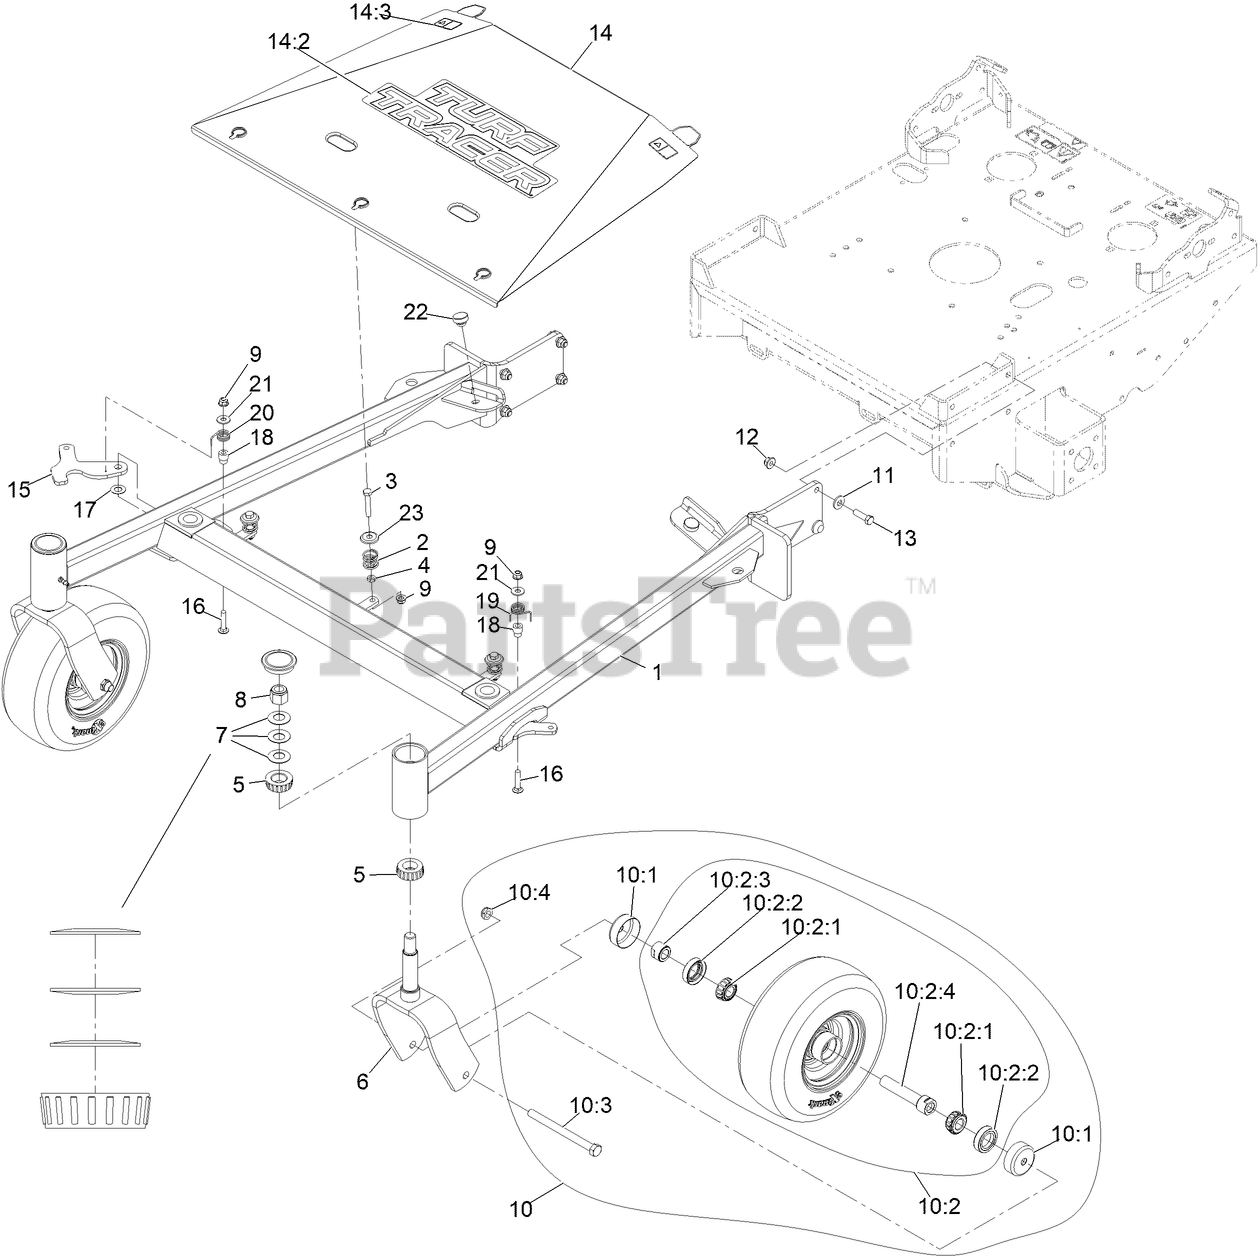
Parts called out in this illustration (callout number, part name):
1	ASM-60" Ttx Front Frame
3	SCREW-HH
4	NUT-JAM
5	Cone-Bearing Tapered Roller
6	WLD, CASTER FORK
7	WASHER-BELLVILLE
8	NUT-LOCK, NI
9	NUT-HF, NI
10	ASM,WHEEL&BEARINGS
10:1	GUARD-SEAL
10:2	Wheel And Bearing ASM
10:2:1	BEARING-CONE, TAPERED ROLLER
10:2:2	SEAL-CASTER
10:2:3	SPACER-NUT
10:2:4	CASTER AXLE ASM
10:3	SCREW-HH
10:4	NUT-HEX
11	WASHER-BELLEVILLE
12	NUT-HF, NI
13	SCREW-HH
14	ASM-60" Ttx Center Shield
14:2	DECAL-TURF TRACER
14:3	DECAL-WARNING
15	LATCH, DECK HEIGHT
16	BOLT-CARR
17	Washer-Plastic
18	COLLAR-BASKET
19	SPRING-TORSION, LH (YELLOW)
20	Spring-Torsion, RH
21	WASHER-FLAT
22	BUMPER-RUBBER
23	Washer-Cup
